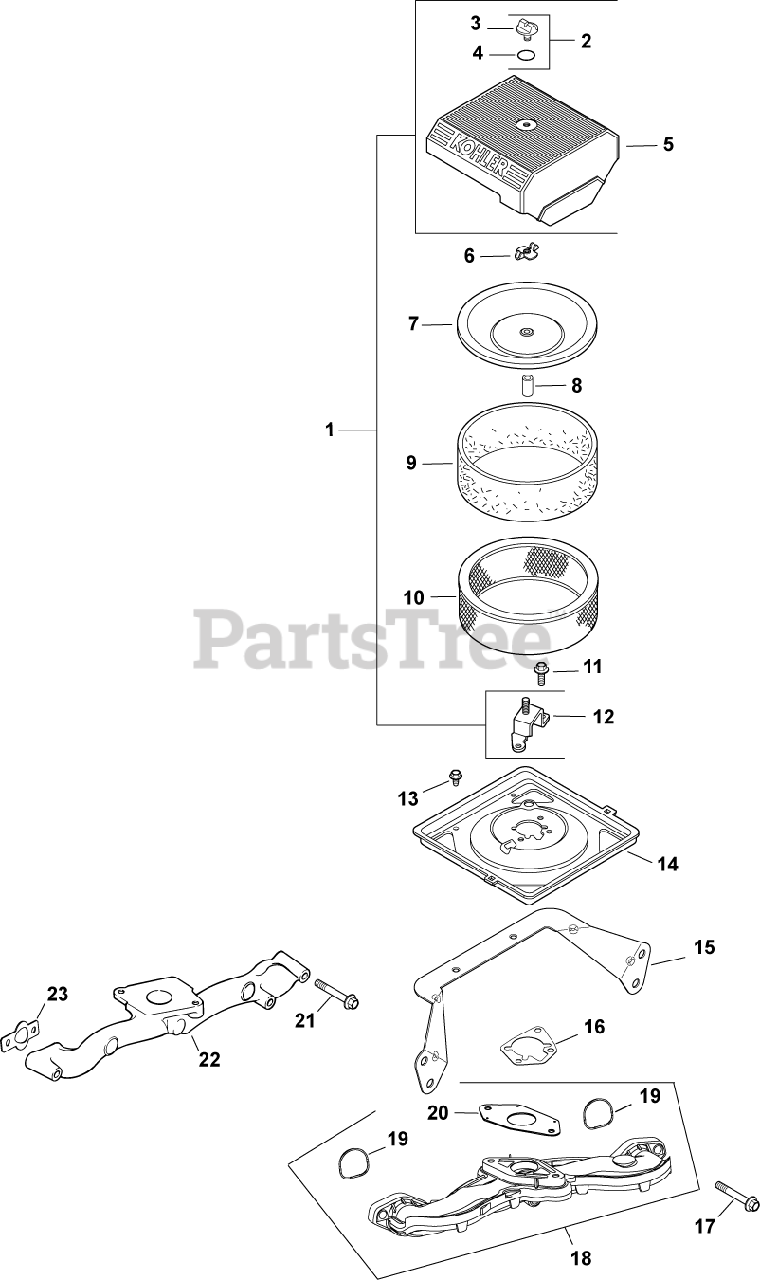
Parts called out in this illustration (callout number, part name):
1	KIT, AIR CLEANER COVER
2	KIT, KNOB W/SEAL
3	KNOB, COVER
5	COVER, AIR CLEANER
6	NUT, WING
7	COVER, INNER AIR CLEANER
8	SEAL, INNER AIR CLEANER
9	ELEMENT, PRECLEANER (LOW)
10	ELEMENT, AIR CLEANER - Also available Retail Packaged 47 883 03-S1 Air Filter Kit
11	SCREW, FLG THD FRM M6X1.0X16
12	BRACKET, AIR CLEANER - DISCONTINUED
13	SCREW, FLG THD FRM M5X.8X10
14	BASE, AIR CLEANER-USE 24 094 84-S
15	BRACKET, AIR CLEANER BASE
16	GASKET, AIR CLEANER BASE
17	SCREW, FLG M6X1.0X40
18	MANIFOLD, INTAKE - PLASTIC-USE 24 164 93
19	O-RING, INTAKE PORT
20	GASKET, CARBURETOR
21	SCREW, FLG M6X1.0X55
22	MANIFOLD, METAL INTAKE
23	GASKET, INTAKE MANIFOLD USE 24 041 79-S
2412621-S	BRACKET,AIR CLEANERBASE-USE 24 126 206-S
